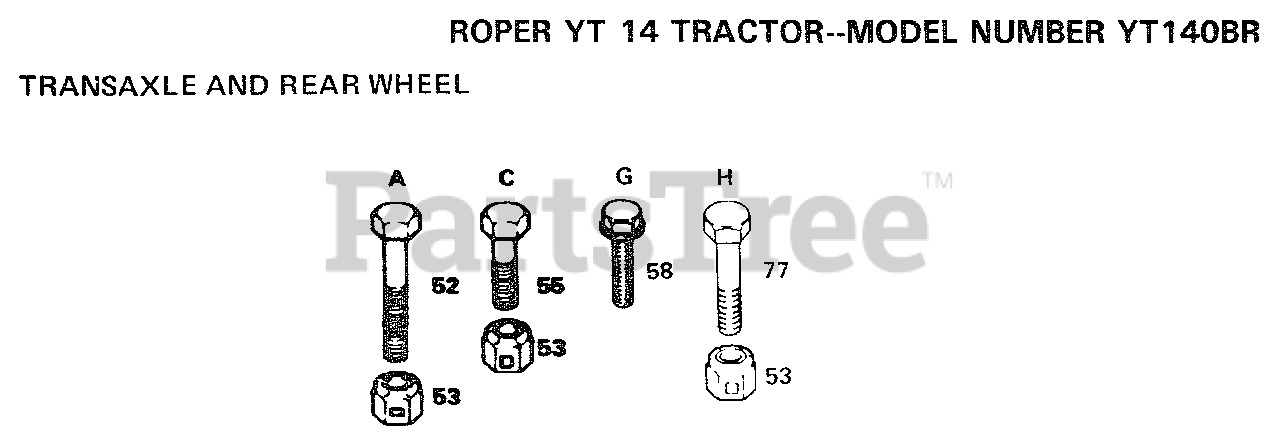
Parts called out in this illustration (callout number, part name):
52	BOLT
58	SCREW
77	BOLT
